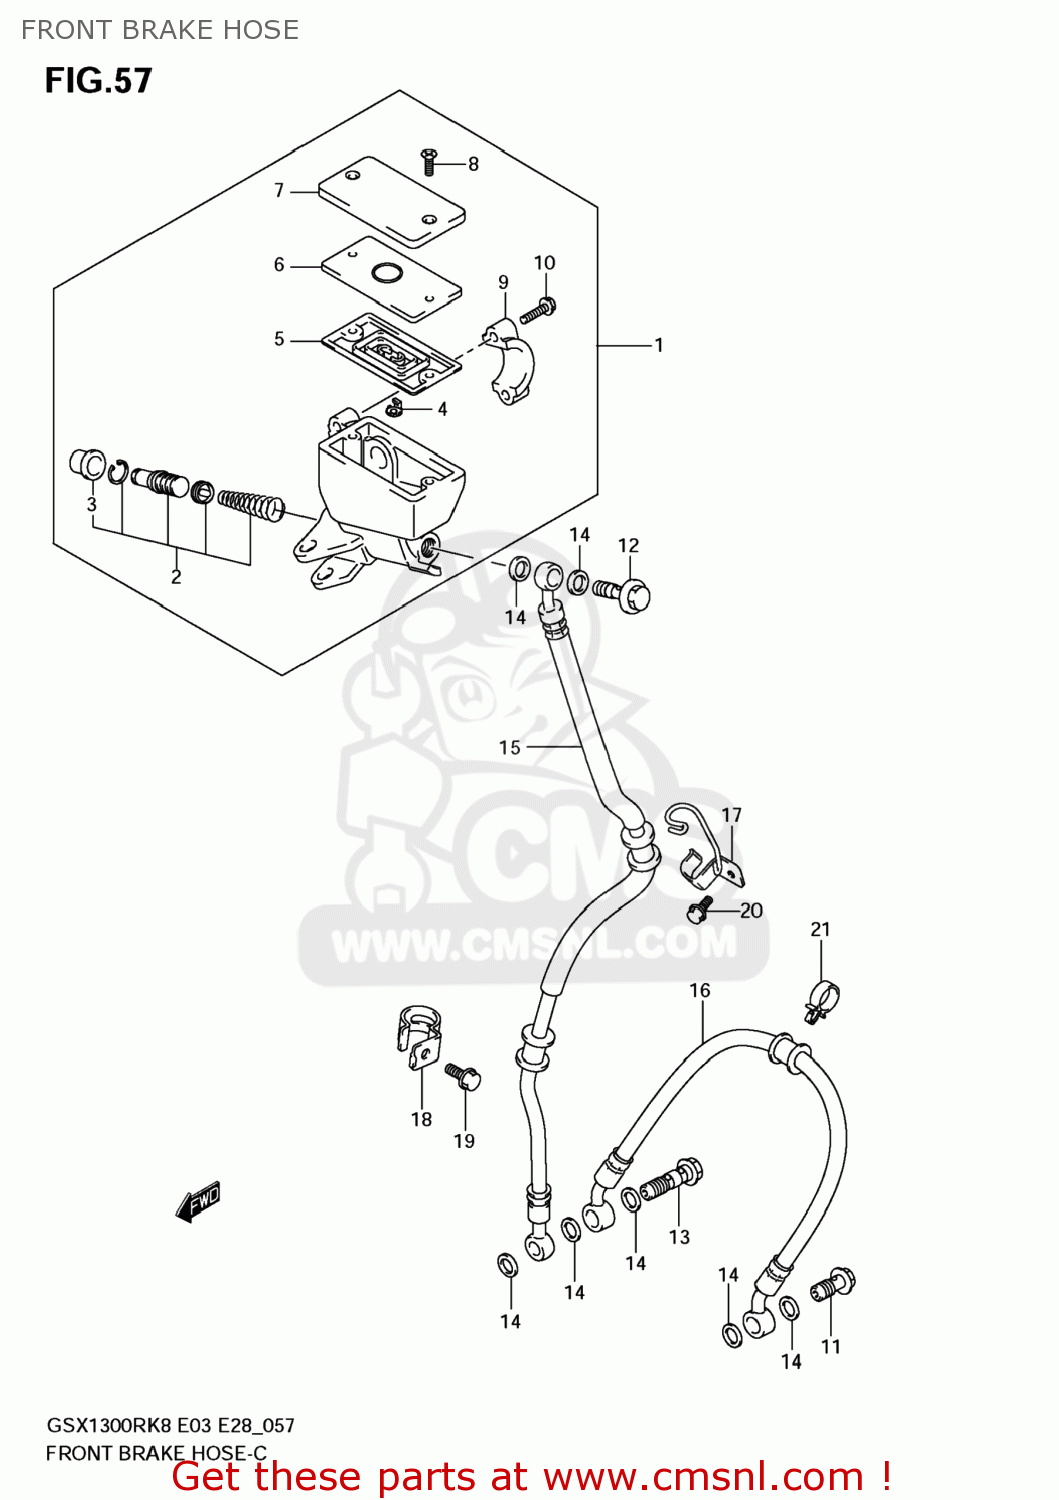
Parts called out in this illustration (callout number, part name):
1	CYLINDER ASSY,FR MASTER
2	PISTON & CUP SET
3	BOOT
4	PROTECTOR
5	6
6	PLATE,DIAPHRAGM
7	CAP
8	SCREW
9	HOLDER
10	BOLT(6X22)
11	BOLT UNION
12	BOLT UNION
13	BOLT UNION
14	WASHER(10X15X1.5)
15	HOSE,FR BRAKE NO.1
16	HOSE,FR BRAKE NO.2
17	CLAMP,FR BRAKE HOSE NO.1
18	CLAMP,FR BRAKE HOSE NO.3
19	BOLT
20	BOLT
21	CLAMP
